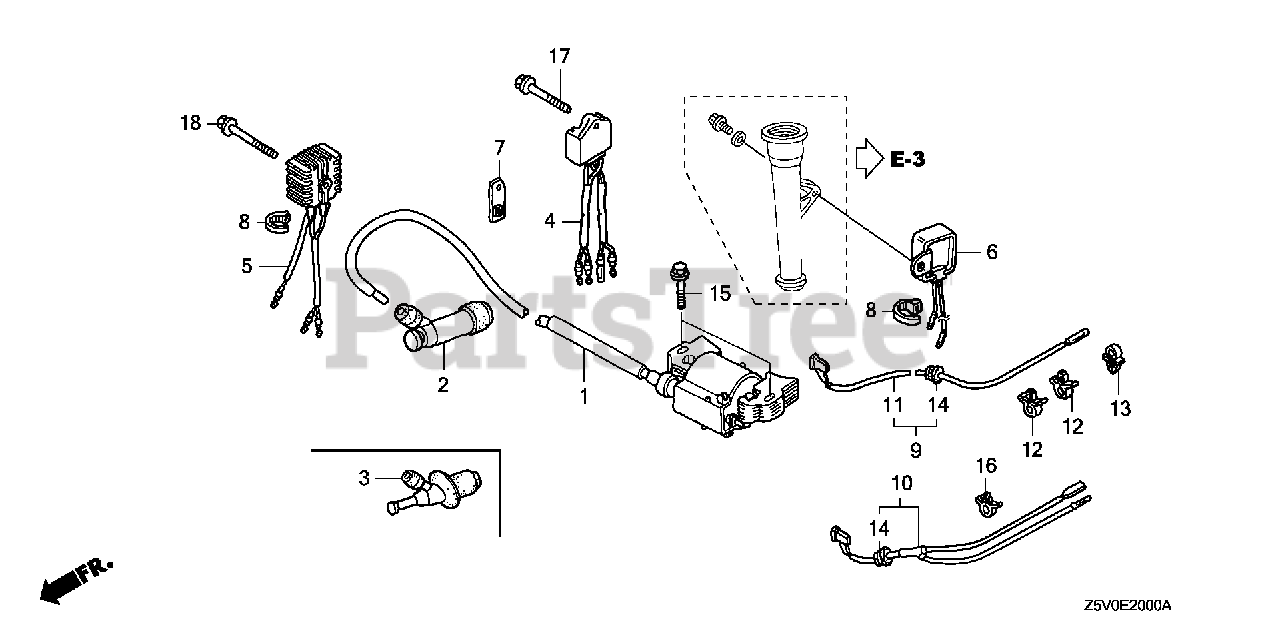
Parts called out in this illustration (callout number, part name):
1	COIL ASSY., IGNITION
2	CAP ASSY., NOISE SUPPRESSOR
10	WIRE, STOP SWITCH
12	CLIP, BRAKE PIPE (A)
13	HOLDER, WIRE (FASTEX)
14	GROMMET, WIRE CORD
15	BOLT, FLANGE (6X28) (CT200)
